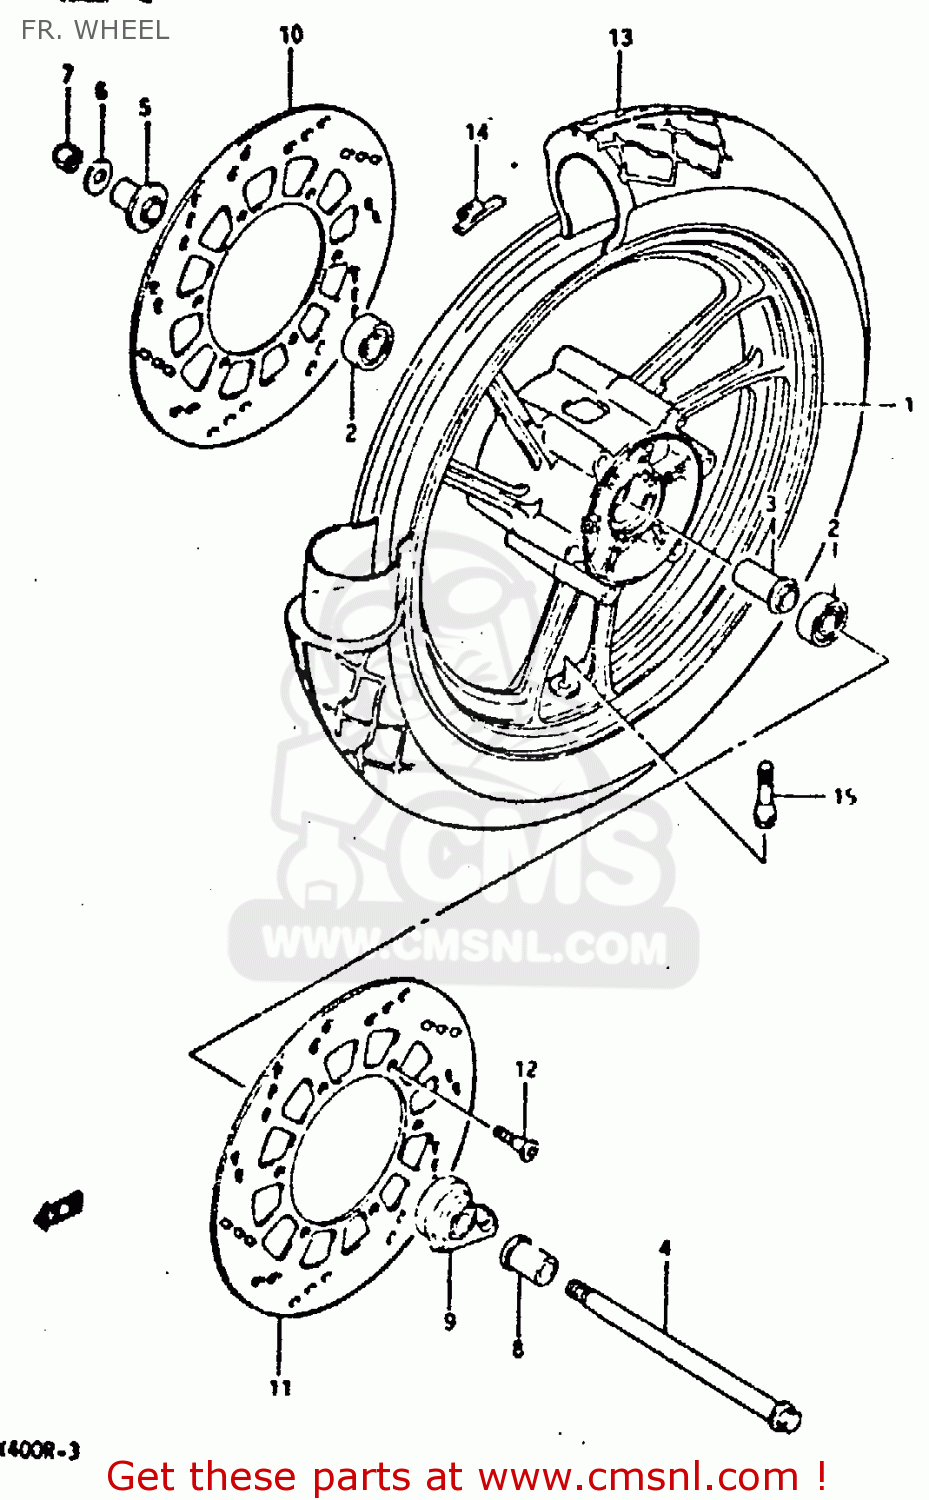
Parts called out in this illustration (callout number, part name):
1	WHEEL,FRONT
2	BEARING
3	SPACER,FR HUB BEARING
4	AXLE,FR
5	SPACER,FR AXLE
6	WASHER
7	NUT 12MM
8	SPACER,FR AXLE,L
9	BOX ASSY,SPEEDOMETER GEAR
10	REMSCHIJF.VOOR
11	VOORREMSCHIJF
12	BOLT(8X25.5)
13	TIRE,FRONT 110/80-17.5
14	BALANCER,WHEEL
15	VALVE,TIRE
